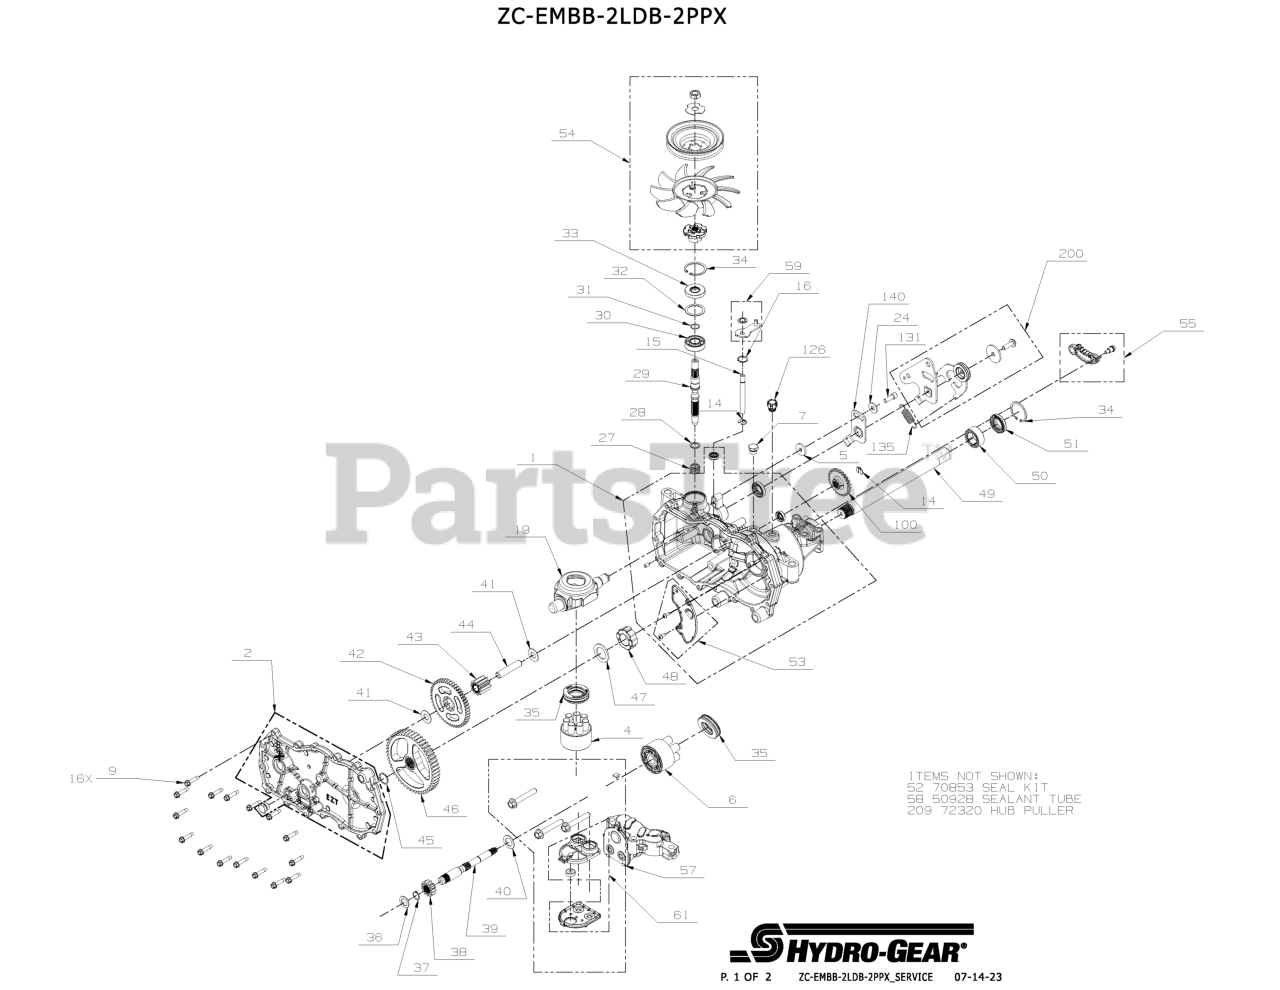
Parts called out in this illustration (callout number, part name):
1	ASSEMBLY, MAIN HOUSING
2	KIT, SIDE HOUSING, RH W/DRAIN
4	ASSY, BLOCK 7 PISTON
6	KIT, 10 CC BLOCK
7	PLUG EXT HEX VENT 9/16 18
9	SCREW,HEX WASHER 1/4-20X1.125
14	RING. RETAINING
15	ROD, BYPASS
16	RING, RET .750
19	TRUNNION, SWASHPLATE
27	SPRING. BLOCK
28	WASHER. THRUST .59 X .79 X .04
29	SHAFT, INPUT
30	BRG, BALL 17X40X12
31	RING, RET WIRE .561 ID
32	WASHER 1.23X1.56X.04
33	SEAL, LIP 17X40X7
34	RING, RET 1.56 INT
35	BEARING. THRUST 30 X 52 X 13
36	WASHER .63X1.0X.05
37	RING, RET 62 EXT
38	GEAR, 13T PINNION
39	SHAFT, MOTOR
40	WASHER .71 X 1.16 X .04
41	WASHER .5X1.0X.032
42	GEAR, 10T/48T
43	GEAR, 10T JACKSHAFT
44	PIN, JACKSHAFT
47	WASHER, 1.018 X 1.571 X .105 FLAT
48	BUSHING, SLEEVE (INBOARD)
49	SHAFT 1.00 X 11.7 D AXLE
52	KIT, SEALS AND RETAINING
53	KIT, EXPANSION PLATE RH
54	FAN PULLEY KIT 4.5X1.625
55	BRAKE ARM-LH, EZT
57	KIT, CENTER SECTION RH
58	SEALANT TUBE 10.1OZ.
59	KIT, BYPASS
61	KIT, FILTER
100	DISC, COG BRAKE
126	ASSEMBLY, FITTING 9/16-18 BREATHER
131	KIT, RTN SCREWS
135	SPRING, EXTENSION
140	ARM, NEUTRAL RIGHT
200	KIT RTN BIDIRECTIONAL
209	HUB PULLER 5 BLT
